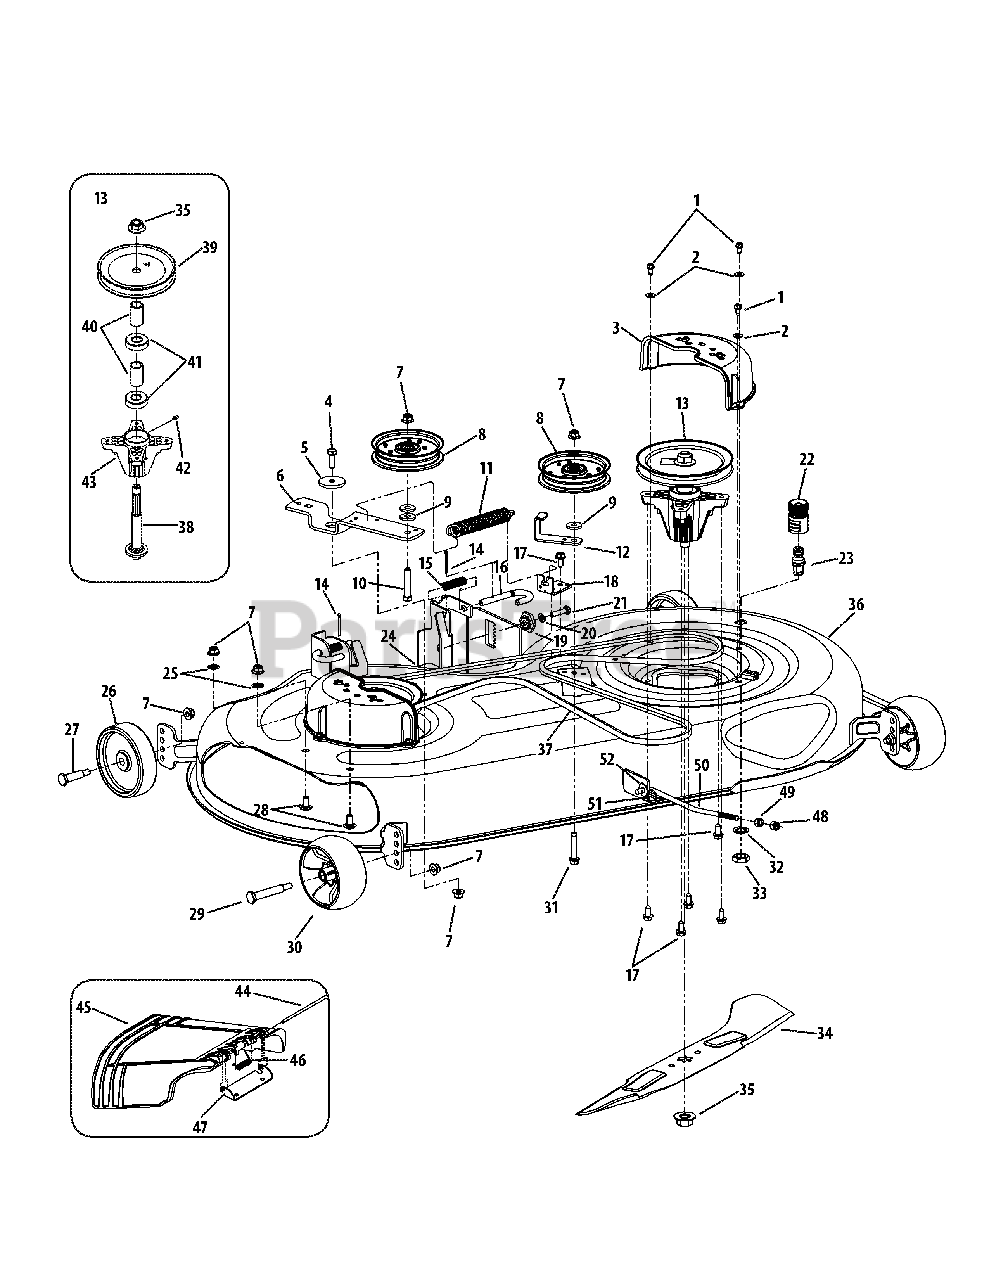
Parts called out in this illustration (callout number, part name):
1	Hex Washer Screw, 1.4-20 x .500
2	Flat Washer, .25 x .630 x .0515
3	Belt Cover
4	Hex Screw, 3.8-16 x 1.00
5	Shoulder Spacer, .8840 x .190
6	Idler Bracket
7	Flange Lock Nut, 3.8-16
8	Idler Pulley
9	Flat Washer, .385 x 1.0 x .135
10	Hex Screw, 3.8-16 x 2.00
11	Extension Spring
12	Belt Guard Bracket
13	Spindle Assembly
14	Cotter Pin, 1.8 x 1.25
15	Compression Spring, .531 x 1.75
16	Deck Handle Rod
17	Hex Washer Screw, 5.16-18 x .750
18	Deck Engage Bracket
19	Deck Adjustment Gear
20	Lock Washer, 5.16
21	Hex Screw, 5.16-18 x 1.25
22	Water Nozzle Adapter
23	Deck Water Nozzle
24	Deck Hanger Bracket Assembly
25	Push Nut, 3.8
26	Deck Wheel
27	Shoulder Bolt, 3.8-16 x .496 x 1.525
28	Carriage Bolt, 3.8-16 x .75
29	Shoulder Bolt, 3.8-16 x .496 x 2.50
30	Deck Wheel
31	Hex Washer Screw, 3.8-16 x 1.875
32	Lock Washer, 5.8
33	Hex Nut, M16-1.5
34	2-in-1 Blade
35	Flange Nut, 5.8-18
36	Deck Assembly
38	Spindle Shaft
39	Deck Pulley
40	Spacer, .792 x 1.060 x 1.860
41	Ball Bearing, .787 x 1.85 x .551
42	Lube Fitting
43	Spindle Housing
44	Hinge Pan, .3125 x 7.96
45	Chute Assembly
46	Torsion Spring, .44 x 2.0
47	Chute Bracket
48	Hex Lock Nut, 1.2-13
49	Hex Nut, 1.2-13
50	Deck Lift Rod
51	Lynch Pin, .1875
52	Flat Washer, 1.2 x 1.25 x .10
